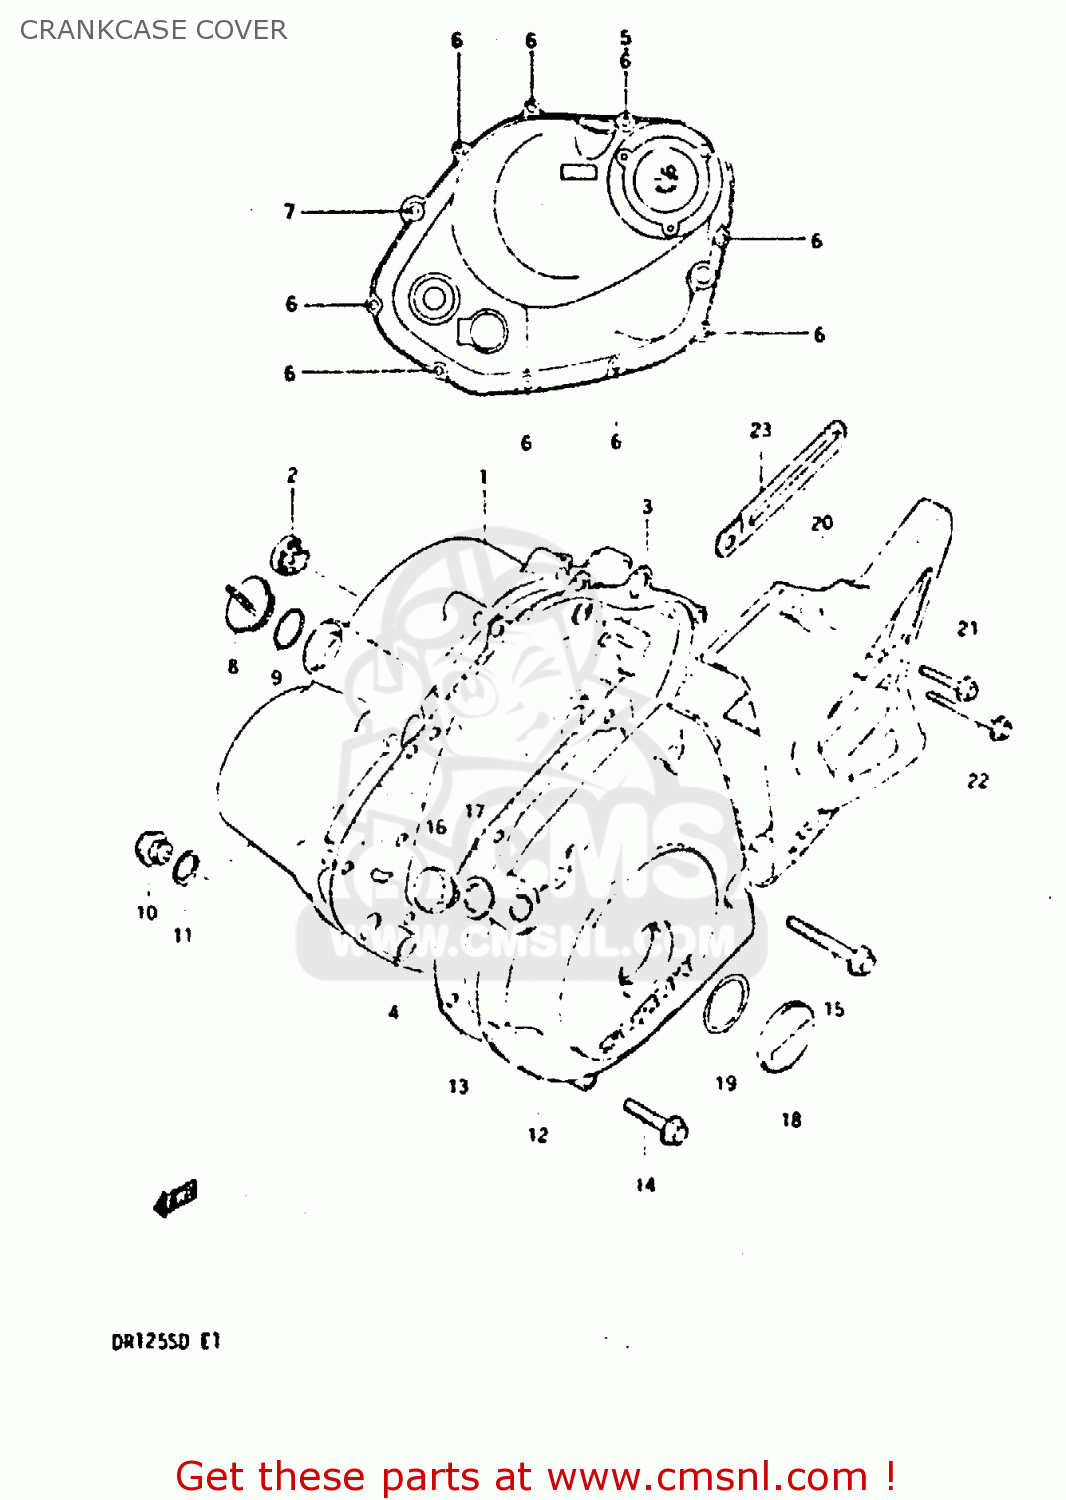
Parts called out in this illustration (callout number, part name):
1	COVER,CLUTCH
2	LENS,OIL LEVEL CHECK
3	GASKET,CLUTCH COVER (MCA)
4	PIN
5	GASKET (NAS)
6	BOLT (6*30)
7	BOLT (6X45)
8	PLUG
9	O RING(D:3.1,ID:16.8)
10	PLUG (14X12)
11	GASKET(14X19.2X2) (NAS)
12	COVER,MAGNETO
13	GASKET,MAGNETO COVER (MCA)
14	BOLT (6*30)
15	BOLT (6X40)
16	PLUG(12X9)
17	GASKET(12.1X16.2X3.7) (NAS)
18	PLUG
19	O RING(D:3.1,ID:22.7)
20	COVER,SPROCKET
21	BOLT
22	BOLT
23	CLAMP
